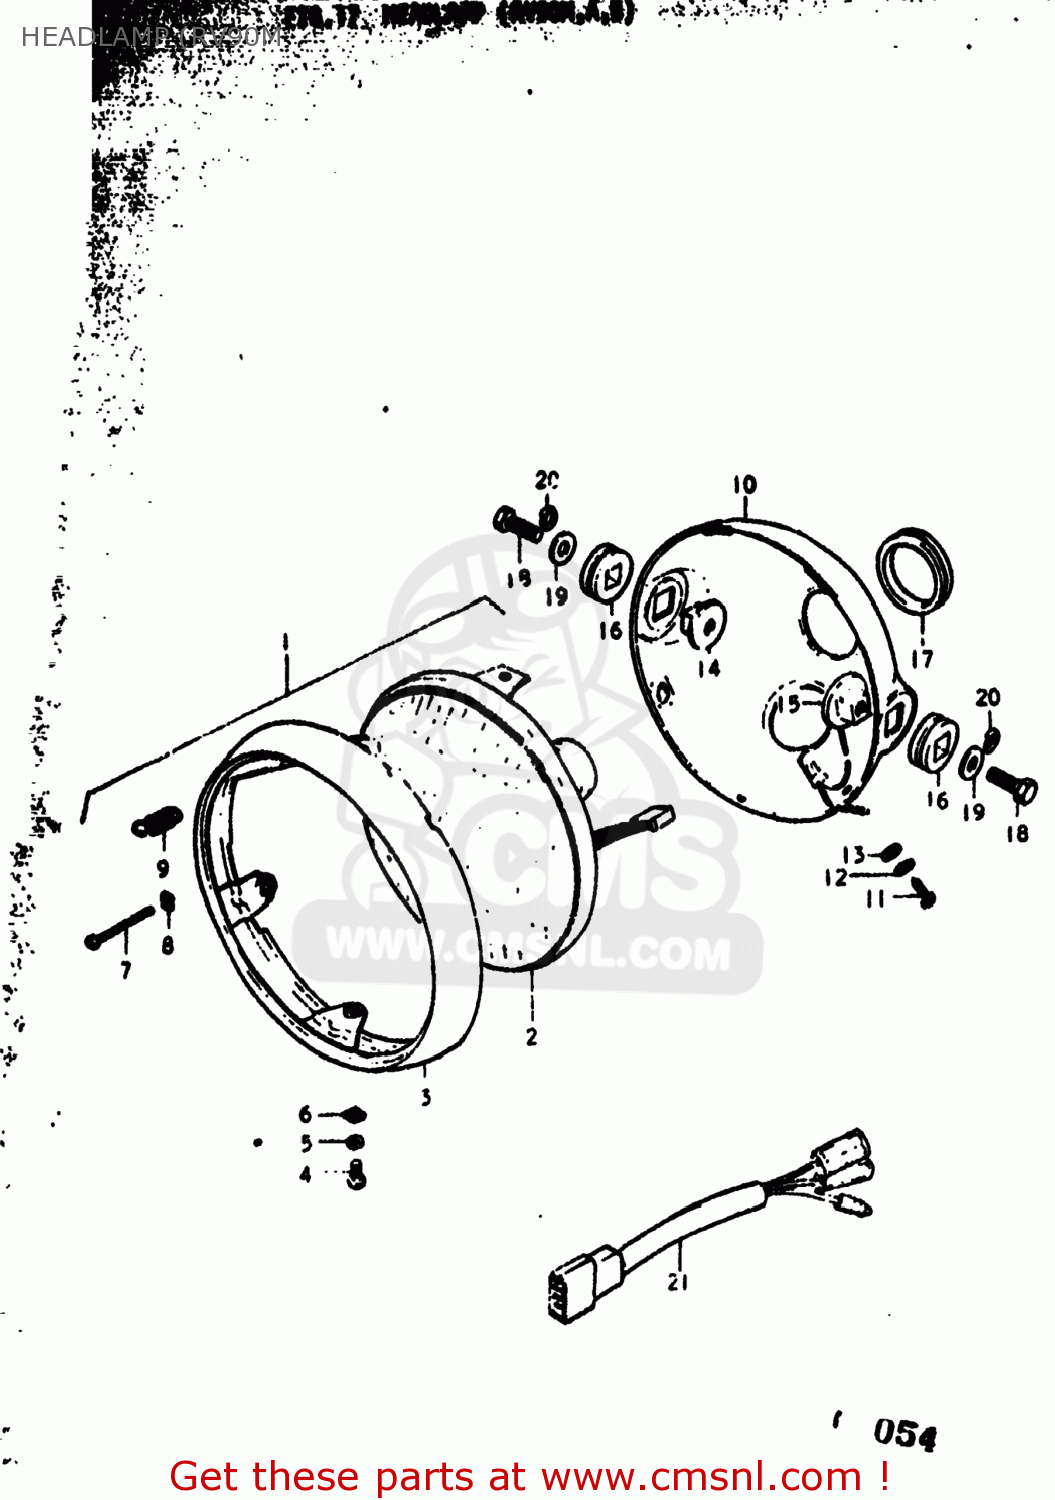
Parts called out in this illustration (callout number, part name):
1	HEADLAMP ASSEMBLY
2	LAMP UNIT
3	RIM,HEADLAMP
4	SCREW
5	SPACER,HEADLAMP UNIT
6	NUT,ADJUSTING
7	SCREW,HEADLAMP ADJUST
8	NUT,HEADLAMP ADJUSTER
9	SPRING,HEADLAMP ADJUST
10	HOUSING COMP,HEADLAMP
11	SCREW
12	LOCK WASHER
13	WASHER
14	SPACER, HOUSING RH
15	SPACER, HOUSING LH
16	CUSHION,HEADLAMP HOUSING
17	GROMMET,HEADLAMP HOUSING
18	BOLT
19	WASHER
20	LOCK WASHER
21	WIRE,HEADLAMP GROUND
